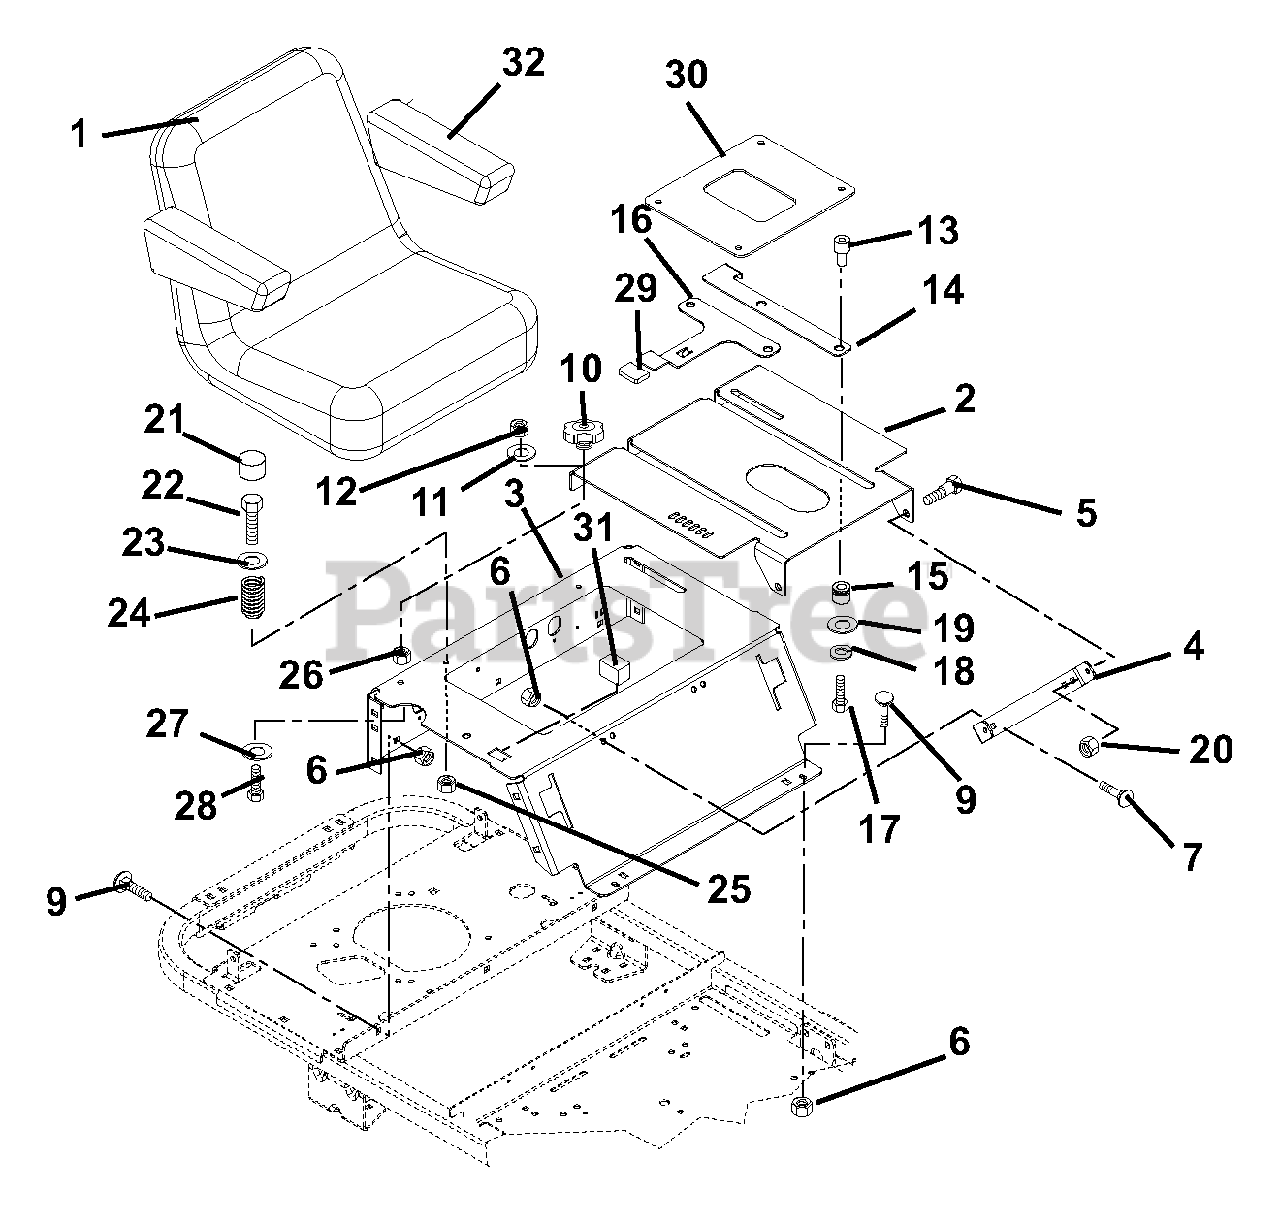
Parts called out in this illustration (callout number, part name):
1	SEAT, TS2500 MICHIGAN W/ARM.
2	SEAT PLATE
3	SEAT BOX
4	BRACKET, SEAT PLATE
5	BOLT-SHLDR .375-16X.150
6	@NUT-LK-NYL-FLG .38-16 YWZC
7	@BLT-RDHDSQNK .38-16X1.00 G5YZ
8	HOURMETER-QUARTZ 80VDCMAX
9	@BLT-RDHDSQNK .38-16X1.00 G5YZ
10	KNOB-CLAMPING, .312-18 NYLOC
11	WSHR-FL-STL .328X1.0X.094 YWZC
12	@NUT-LK-NYL .312-18 YWZC
13	SPACER, SEAT TOP
14	SEAT STOP
15	SPACER, SEAT BOTTOM
16	LEVER, SEAT ADJUSTMENT
17	@BLT-HEX .31-18X2.25 GR5 YWZC
18	@WSHR-LK .31X.078 REG YWZC
19	WSHR-FL-STL .344X1.375X.075YWZ
20	@NUT-LK-TOP-FLG .38-16 YWZC
21	HUB CAP
22	@BLT-HEX .31-18X1.00 GR5 YWZC
23	@WSHR-FL-STL.344X.688X.065YWZC
24	SG. COMP 2.9L X 2.02OD 200LB
25	@NUT-LK-NYL-FLG .31-18 YWZC
26	@NUT-SPNLK-FLG .312-18 YWZC
27	WSHR-FL-STL .505X1.00X.062YWZC
28	@BLT-RDHDSQNK .31-18X3.50 G5YZ
30	SEAT SUPPORT PLATE
31	PLUG, HOUR METER
32	ARMREST KIT
